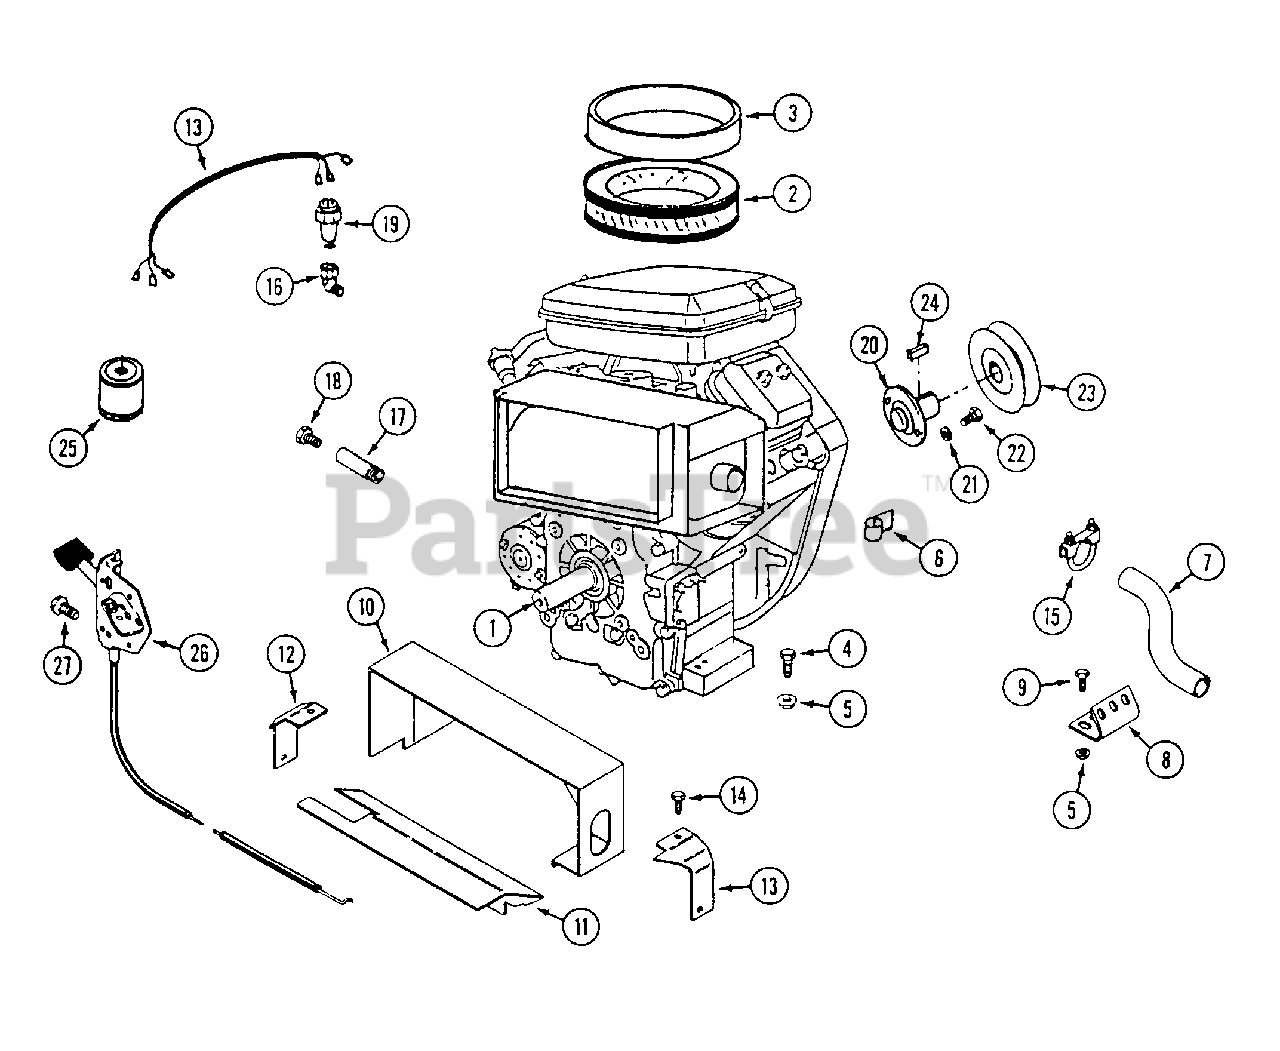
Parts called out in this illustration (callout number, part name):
1	ENGINE - Briggs & Stratton Model 350447, (18 hp)
2	ELEMENT - air cleaner
3	PRE-CLEANER
4	BOLT - 5/16" - 18 x 1-1/4"
5	NUT - 5/16" - 18 flange lock
6	CLIP - "J"
7	PIPE - exhaust
8	BRACKET - exhaust pipe
9	BOLT - 5/16" - 18 x 1"
10	DUCT - muffler, upper
11	DUCT - bottom
12	SUPPORT - duct front
13	SUPPORT - duct rear
14	SCREW - M6 x 10
15	CLAMP - exhaust
16	FITTING - street elbow, 1/4" NPT 45°
17	NIPPLE - pipe 3.5"
18	PLUG - 1/2" - 20
19	UNIT - oil sending
21	LOCKWASHER - 3/8"
22	BOLT - 3/8" - 16 x 1"
23	PULLEY - engine
24	KEY - 1/4" x 1/4" x 1"
25	FILTER - oil
26	CABLE - throttle
27	SCREW - #12 x 1/2"
